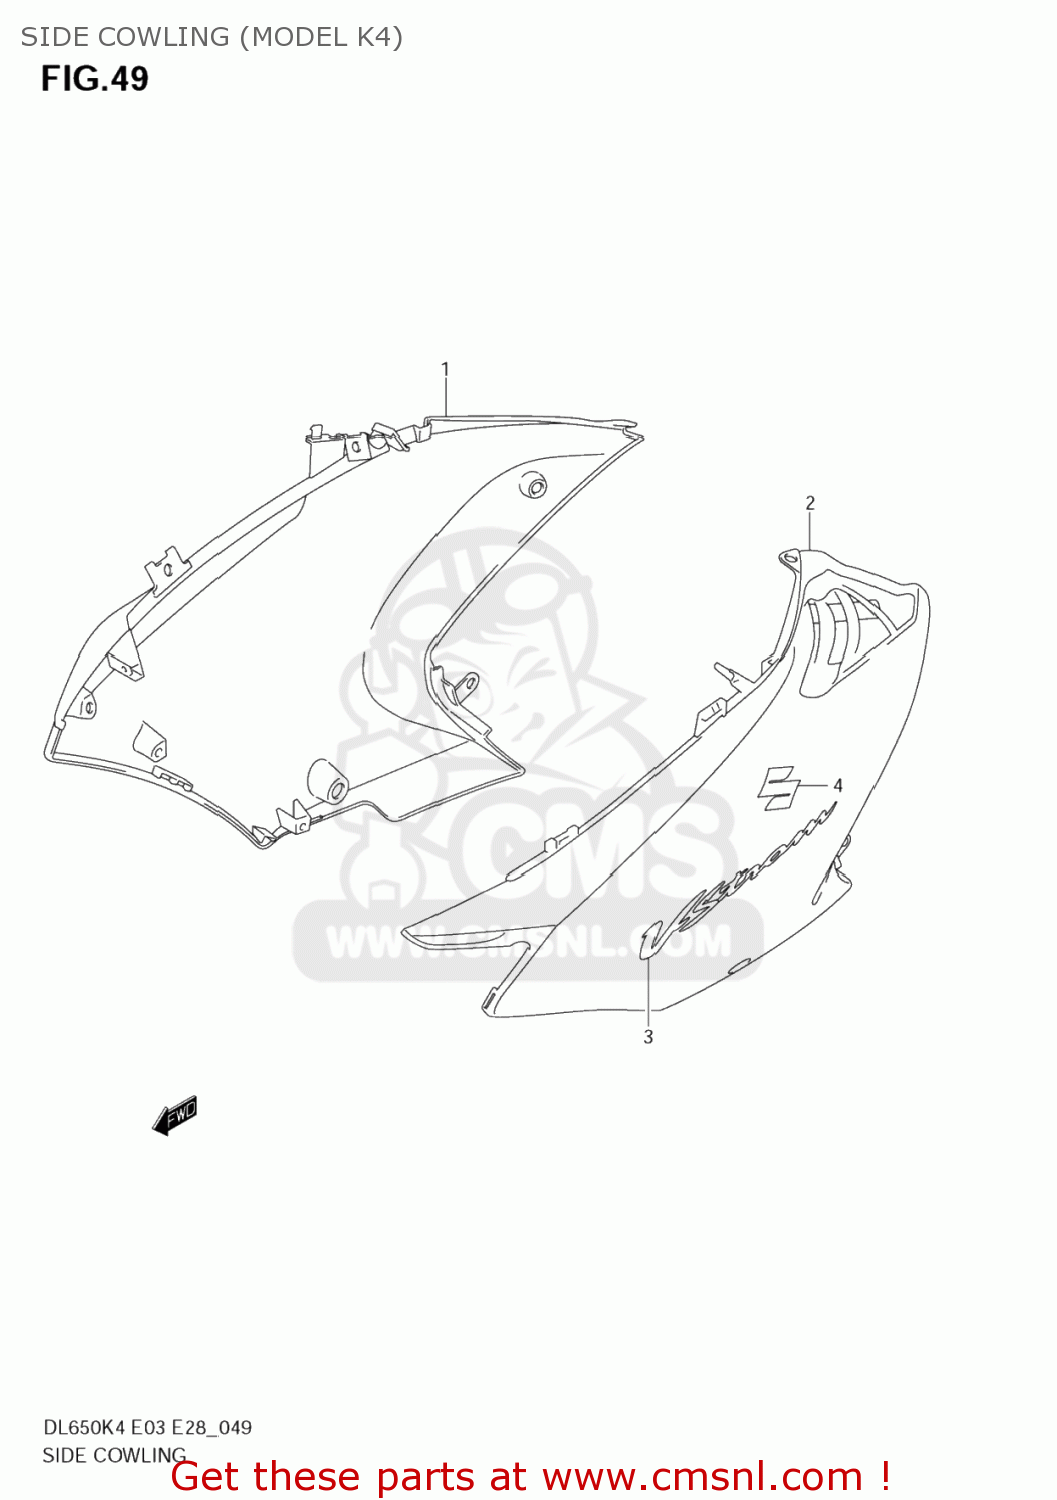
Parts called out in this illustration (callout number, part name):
1	COWLING ASSY,SIDE,R
2	COWLING ASSY,SIDE,L
3	EMBLEM,COWLING SIDE
4	EMBLEM,"S"
